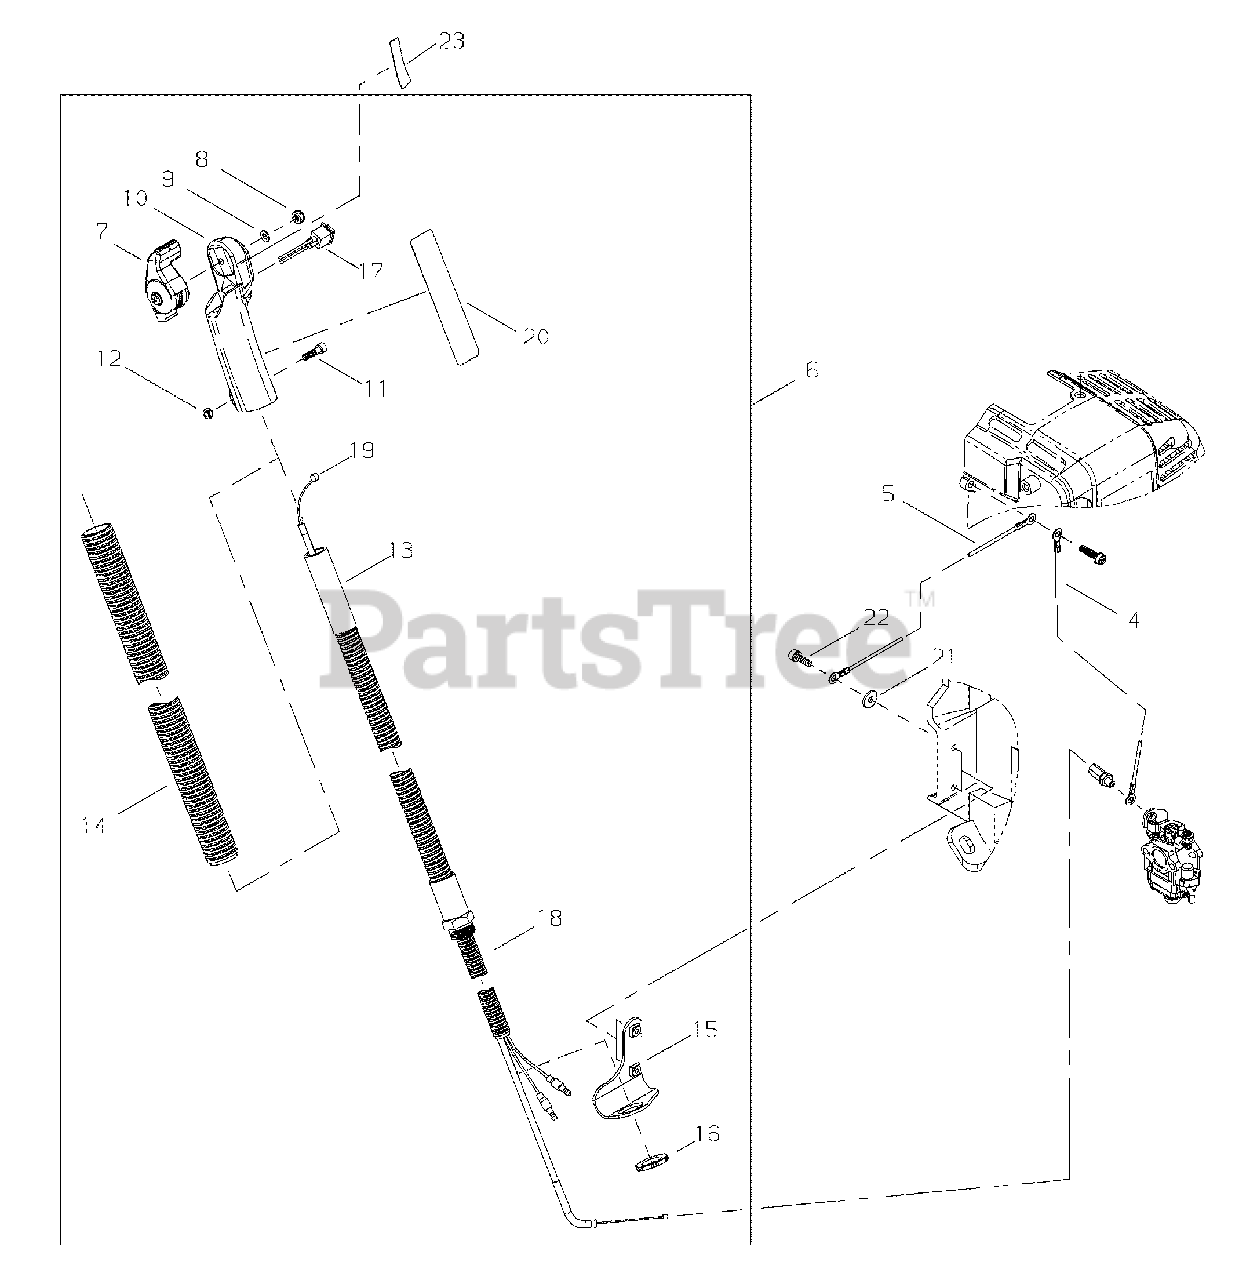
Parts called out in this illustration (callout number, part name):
4	LEAD - ANTI-STATIC - 110mm
5	LEAD - GROUND
6	THROTTLE ASSY
7	THROTTLE LEVER ASSY
8	NUT - 5
9	WASHER - 5
10	GRIP
11	SCREW - 5X20
12	NUT - 5
13	FLEX ARM
14	TUBE, PROTECTIVE
15	BRACKET, MOUNTING
16	NUT - 21
17	IGNITION SWITCH ASSY
18	FLEX TUBE
19	CABLE, THROTTLE
20	PLATE - GROUND
21	COLLAR
22	SCREW - 5X18
23	LABEL - INSTRUCTION
